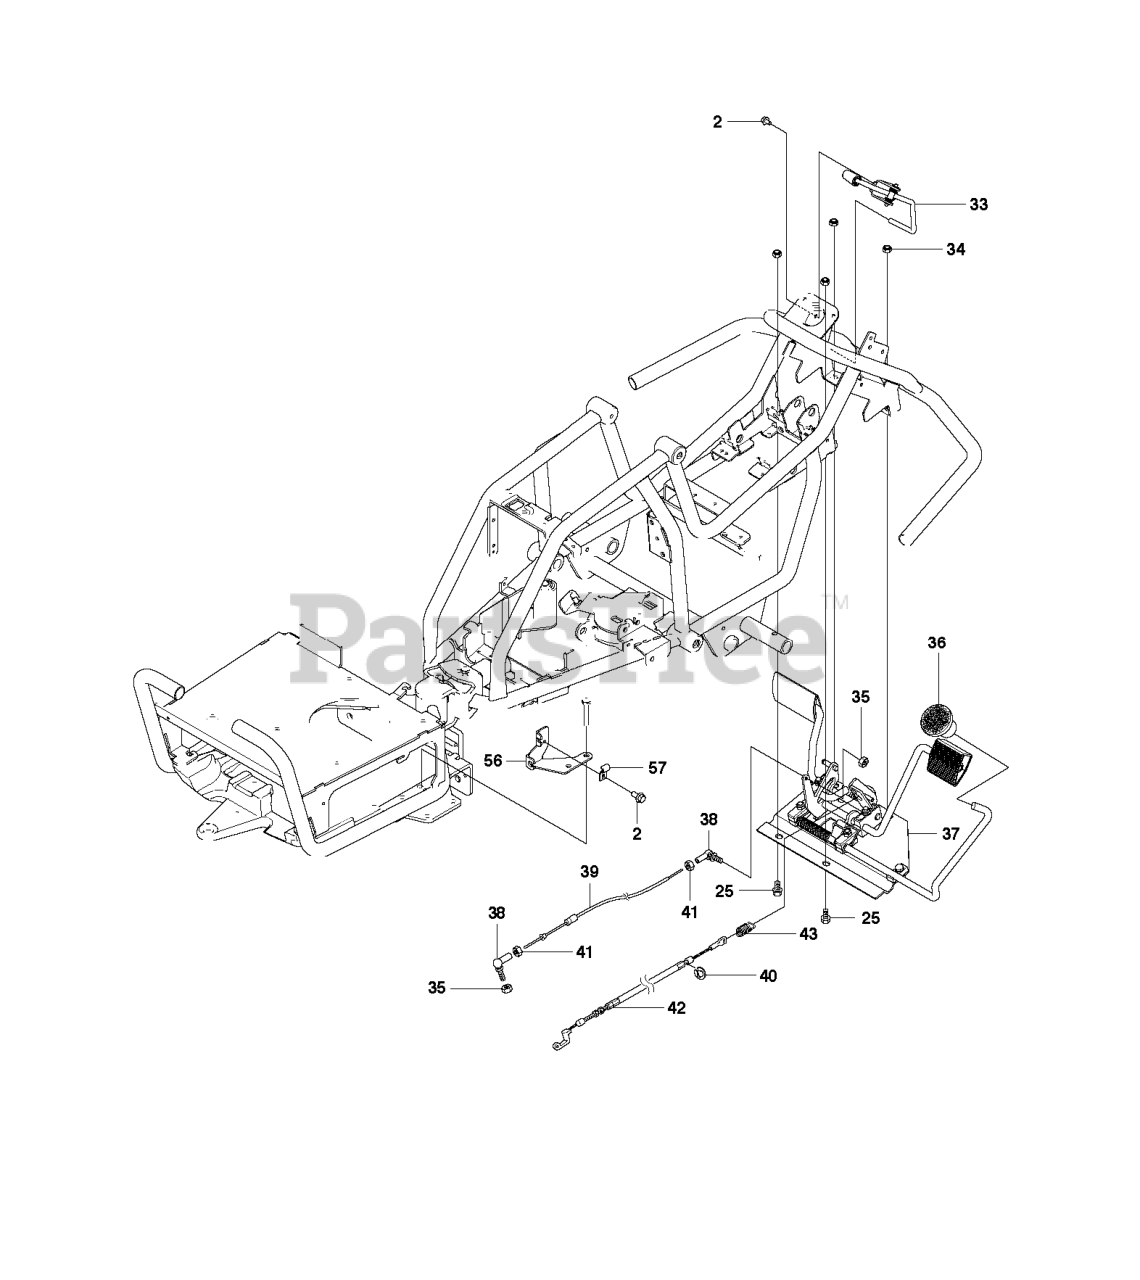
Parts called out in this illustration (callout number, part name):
33	LOCKING LEVER
36	KNOB
37	PEDAL ASSEMBLY
38	CONNECTOR
39	CONTROL CABLE
41	LOCKNUT M5
56	WIRE HOLDER
